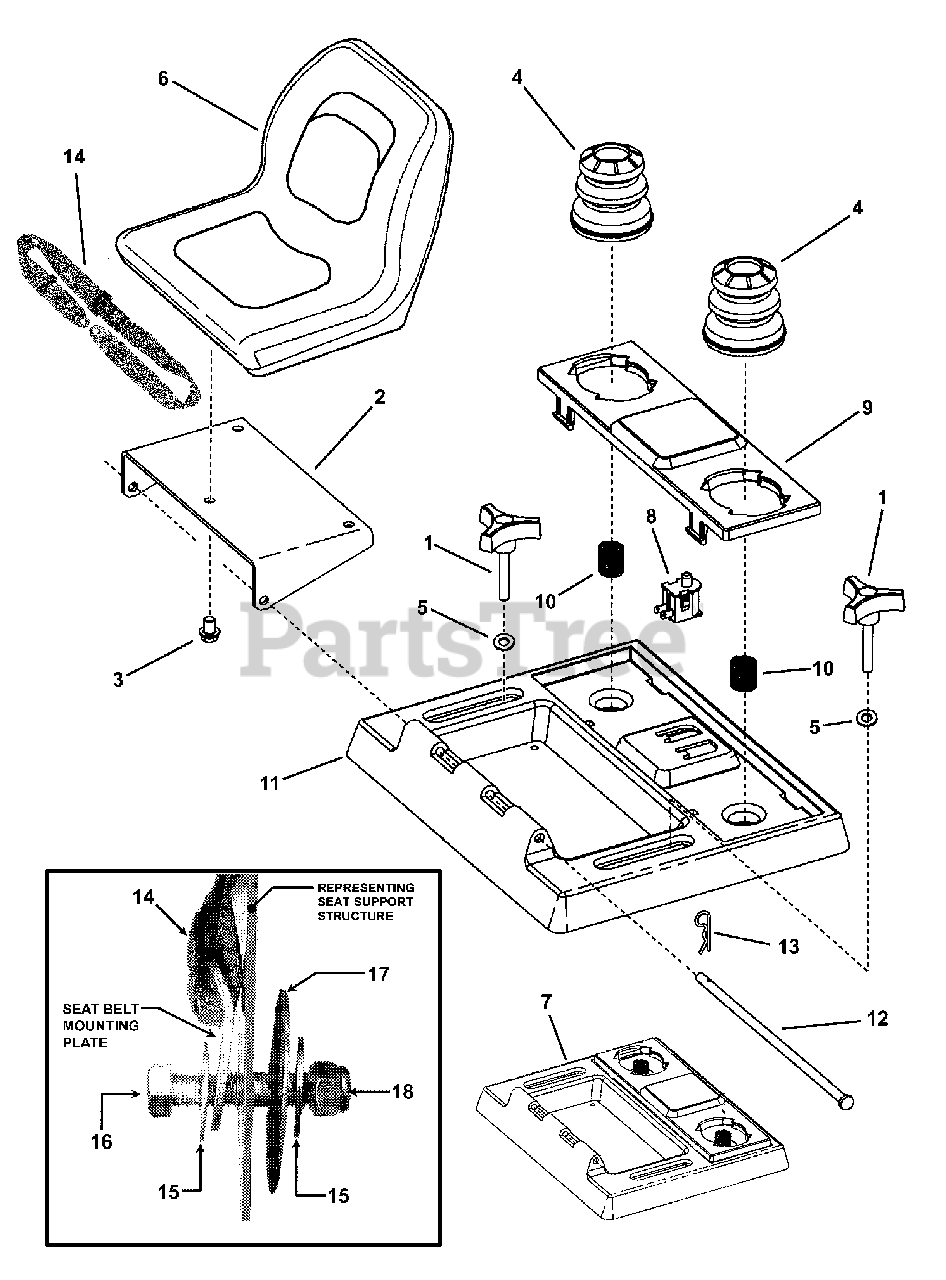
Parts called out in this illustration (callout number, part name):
1	KNOB, 3 Prong, 5/16-18 x 2 Stud
2	SUPPORT, Seat, Upper
3	BOLT, Hex Flange Lock, 5/16-18 x 1/2 GR 5
4	COVER, Spring (Rubber)
5	WASHER, .34 x .69 x .08 Flat
6	SEAT, Milsco XB-150, No Logo
7	ASSEMBLY, Seat Support, UV2 (Includes Ref. Nos. 8 thru 11)
8	SWITCH, Seat
9	HOLDER, Seat Cushion E.C.
10	SPRING, Cushion Holder
11	SUPPORT, Seat E.C.
12	ROD, Seat Hinge
13	HAIR PIN, 3/32 x 1-1/2
14	SEAT BELT
15	WASHER, 7/16 Flat (Type A, Wide)
17	WASHER, 1/2 I.D. x 2-1/2 O.D. Flat
